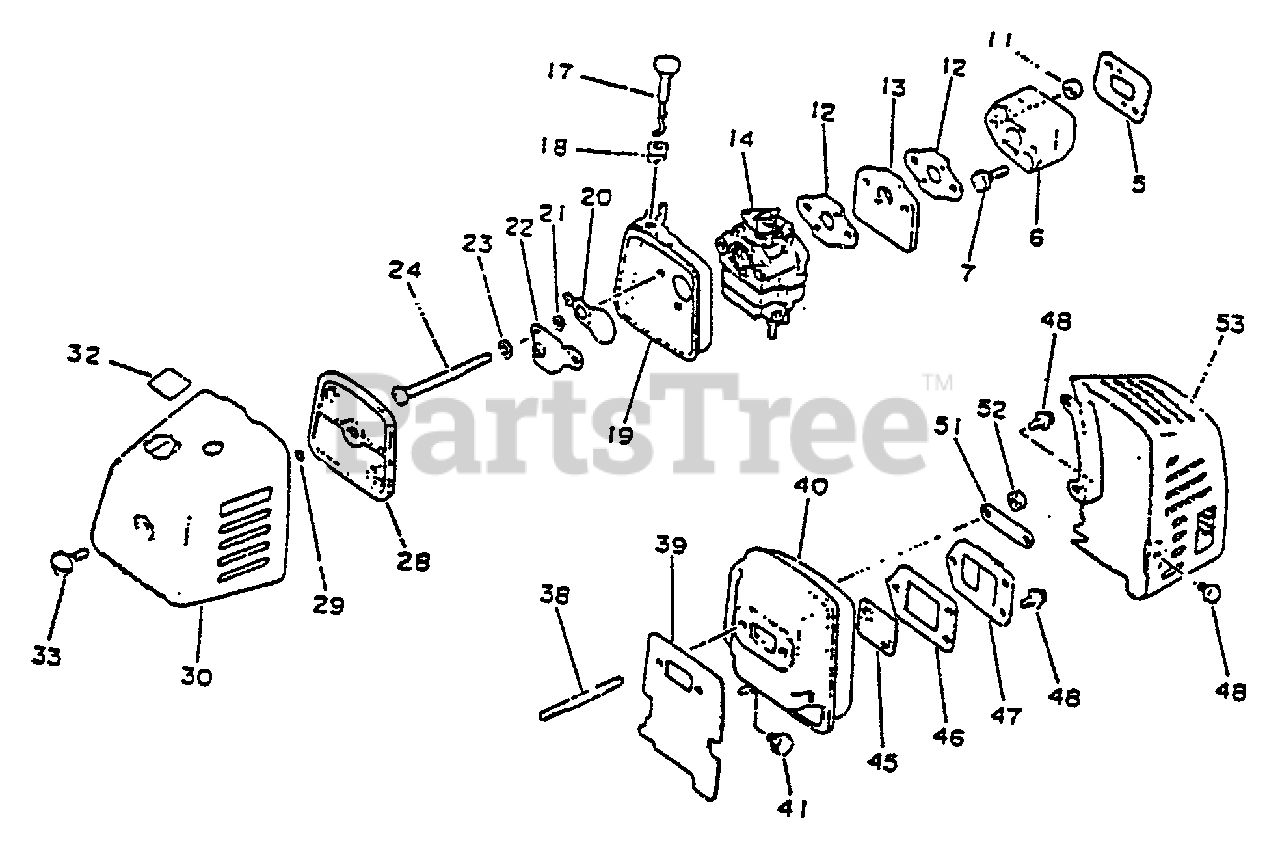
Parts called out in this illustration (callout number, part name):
5	GASKET, INTAKE
6	INSULATOR, INTAKE
7	SCREW - 5X20
12	GASKET, INTAKE
13	INSULATOR
14	CARBURETOR WY-18
17	ROD, CHOKE
19	CASE, AIR FILTER
20	SHUTTER, CHOKE
21	WASHER - 5
22	PLATE, PREVENT
23	LOCKWASHER - 5
24	SCREW - 5X60
28	FILTER, AIR
29	O-RING - 4
30	AIR FILTER COVER ASSY
32	LABEL - CHOKE
39	GASKET, EXHAUST
41	SCREW - 5X10
45	SCREEN, SPARK ARRESTOR
46	GASKET, EXHAUST
47	GUIDE, EXHAUST
48	SCREW - 4X10
52	LOCKNUT - 5
53	COVER, EXHAUST
